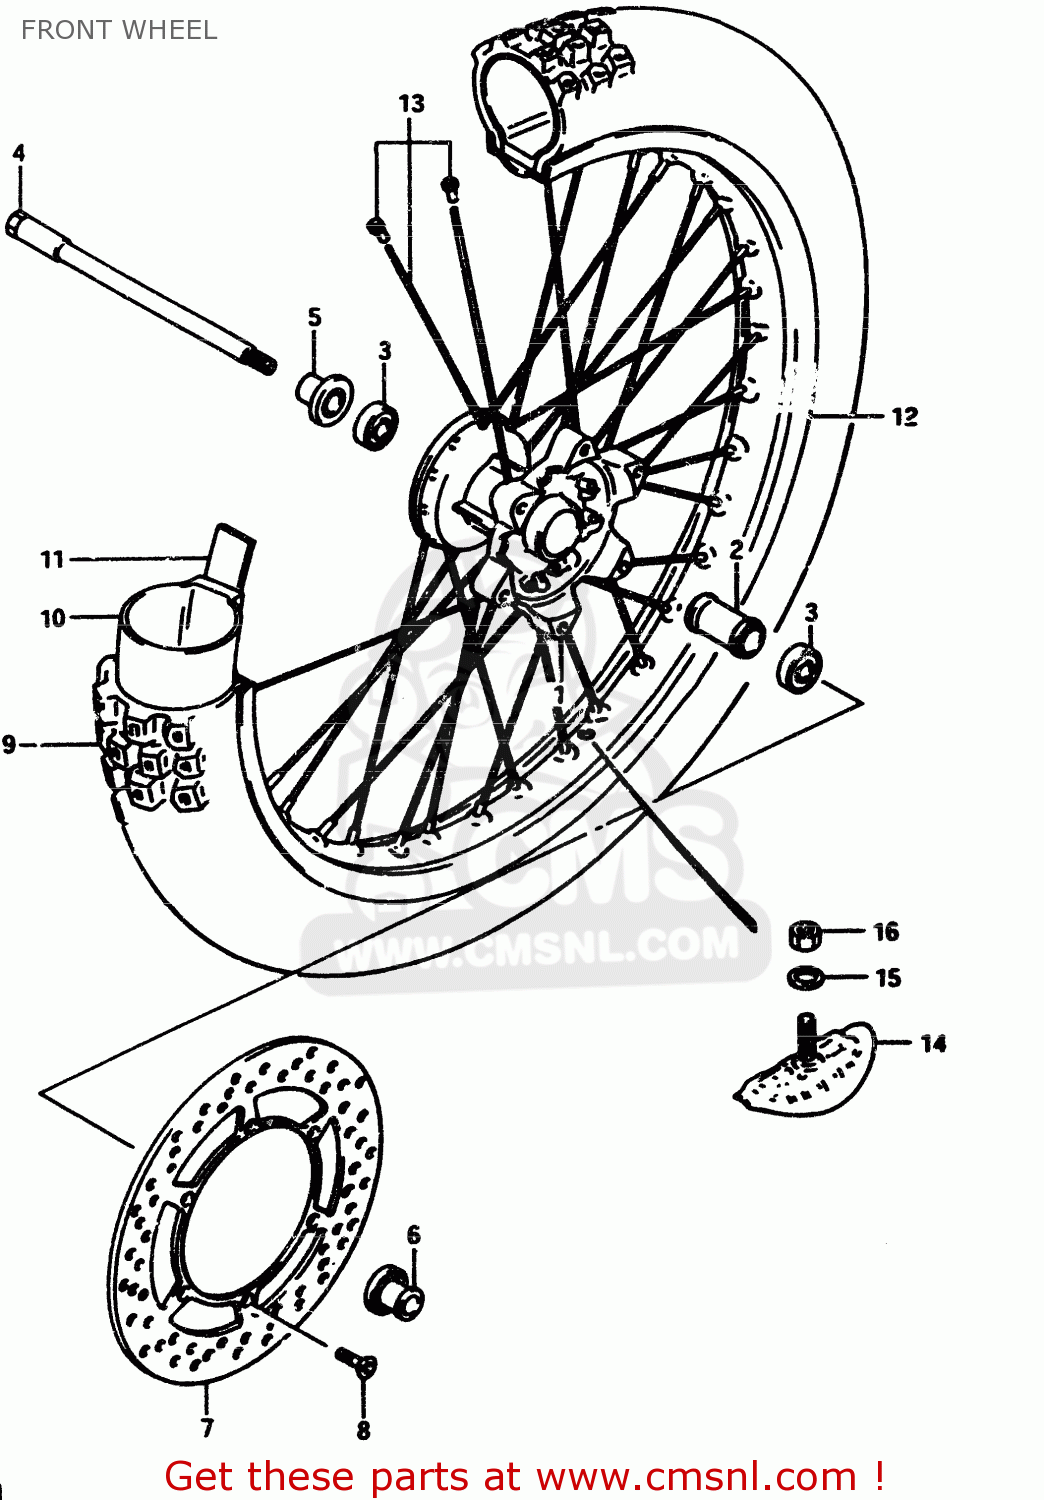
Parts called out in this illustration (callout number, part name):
1	HUB,FRONT
2	SPACER,FRONT HUB BEARING
3	BEARING
4	AXLE,FRONT
5	SPACER,FRONT AXLE,RIGHT
6	SPACER,FRONT AXLE,LEFT
7	DISC,BRAKE
8	SCREW
9	TIRE,FRONT
10	TUBE,INNER
11	PROTECTOR,WHEEL,INNER
12	RIM,FRONT WHEEL (1.60X21)(
13	SPOKE SET,FRONT
14	STOPPER,BEAD
15	WASHER
16	NUT
